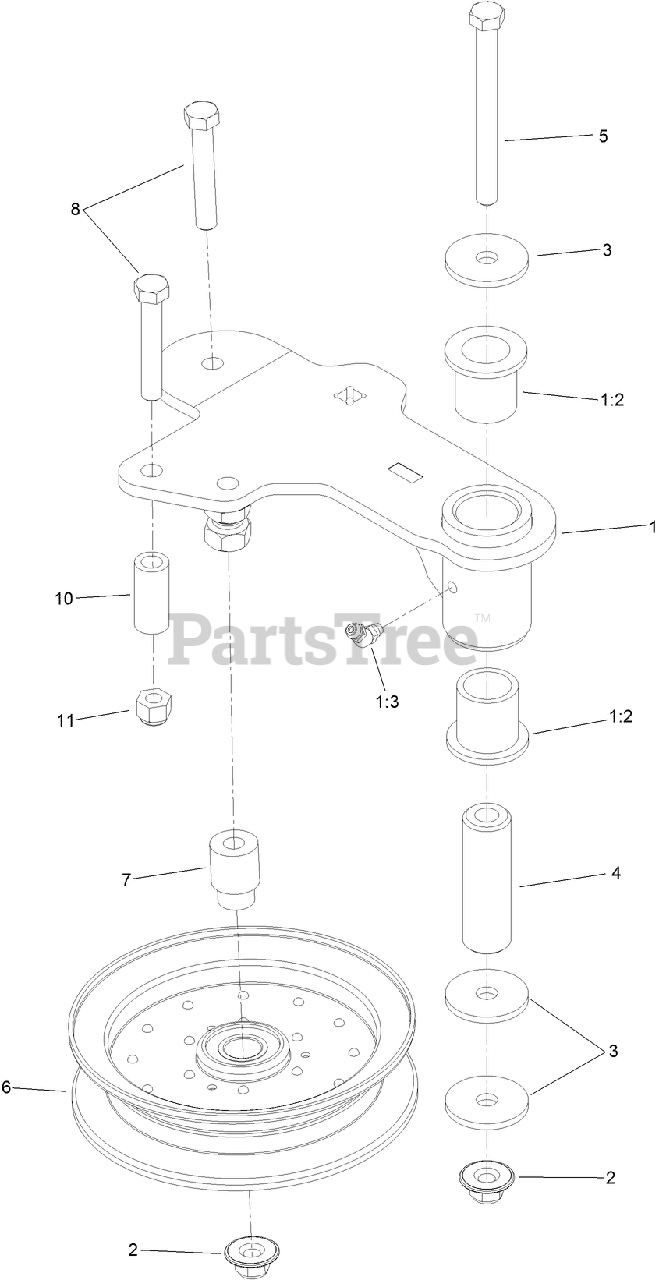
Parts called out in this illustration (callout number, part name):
1	IDLER ARM ASM
1:2	BEARING-FLANGED
1:3	FITTING-GREASE
2	NUT-FLANGE, NI
3	WASHER
4	SPACER-PLAIN
5	SCREW-HH
6	IDLER-PULLEY, FLANGED
7	MOUNT-PULLEY
8	SCREW-HH
10	SPACER
11	NUT-LOCK, NI
